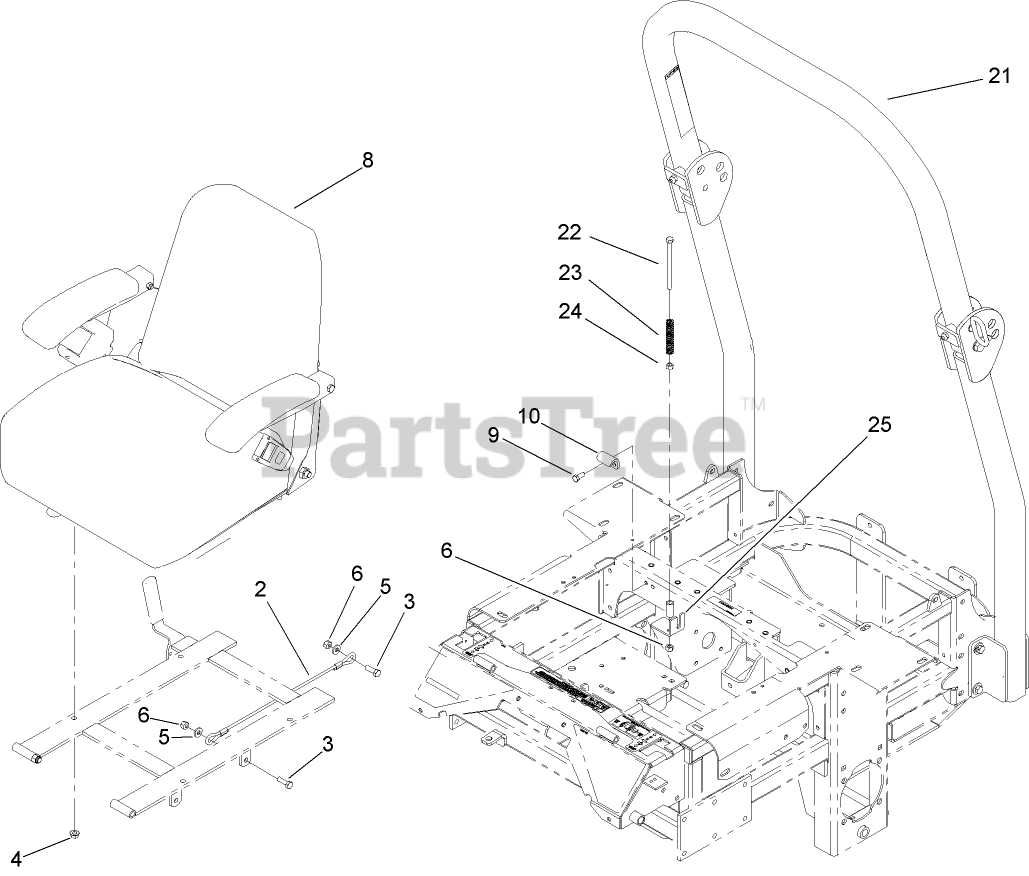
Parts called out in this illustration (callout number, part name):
2	CABLE-SEAT
3	SCREW-HH
4	NUT-HF
5	WASHER
6	NUT-LOCK, NI
8	SEAT ASM
9	SCREW-HH
10	Catch-Latch, Seat
21	ROPS KIT
22	SCREW-HH
23	SPRING-SWITCH, SEAT
24	NUT-HEX
25	PLATE-SWITCH, SEAT
